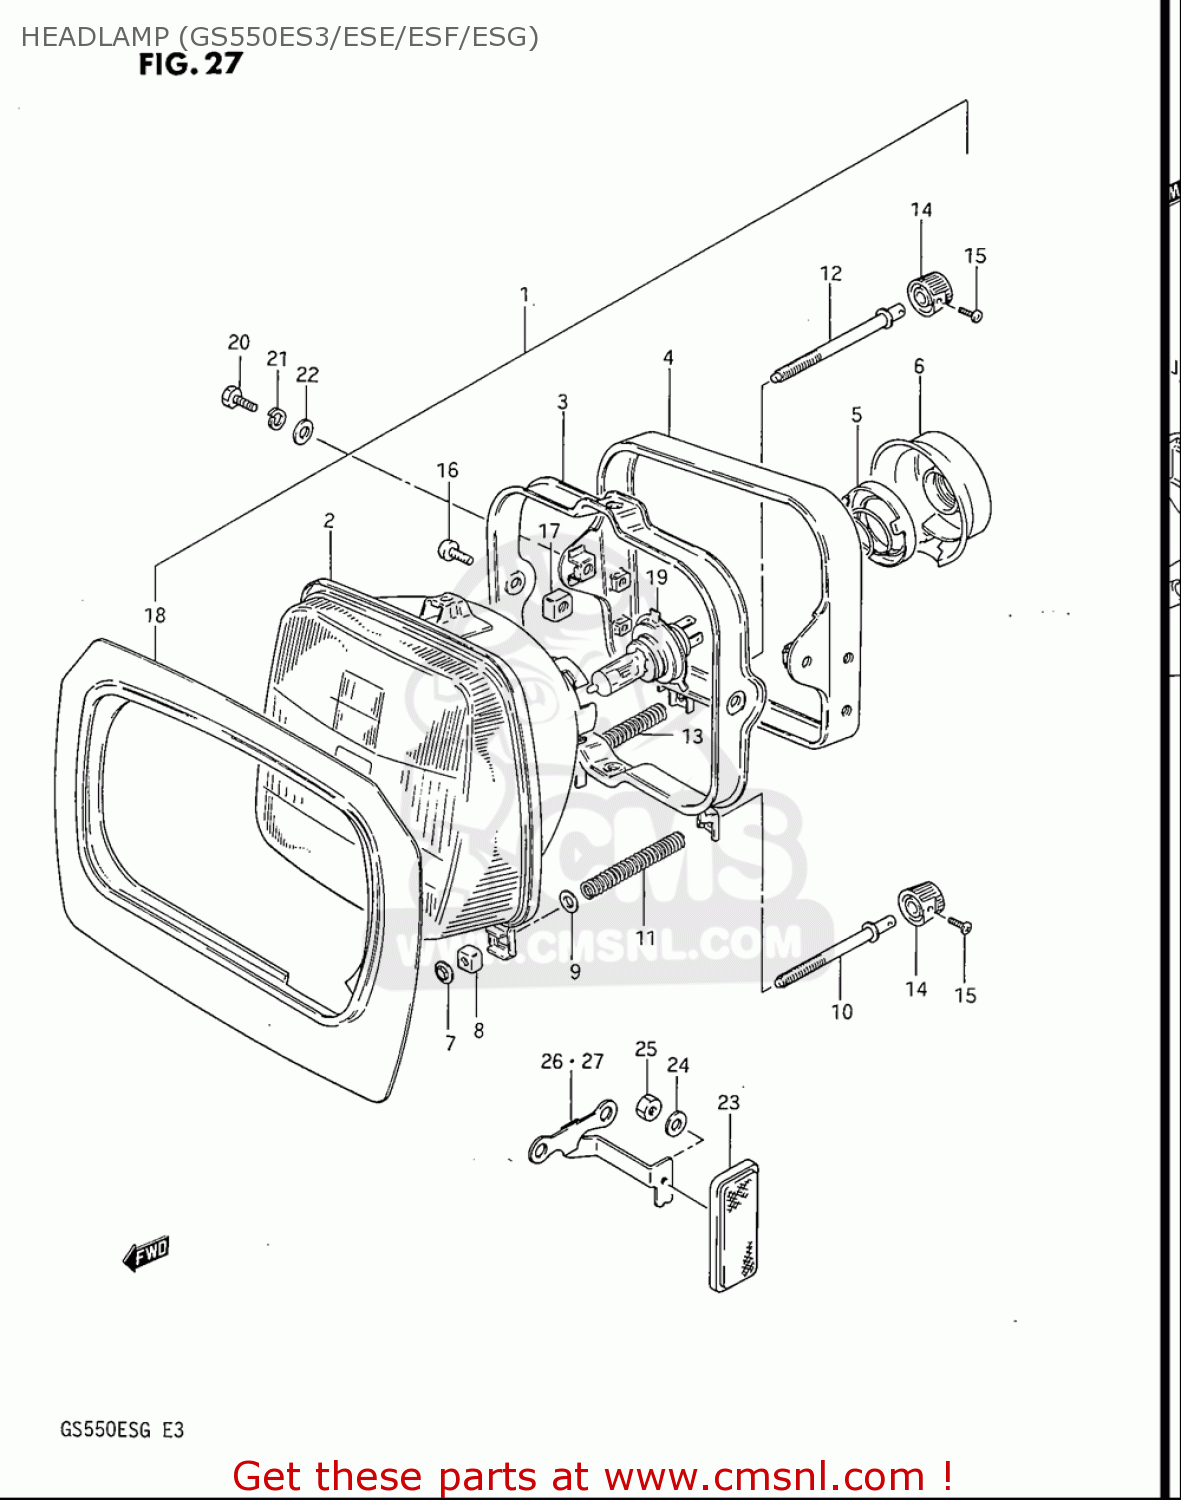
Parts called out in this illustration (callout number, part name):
3	RING,MOUNTING
5	HOLDER
6	COVER,SOCKET
7	NUT
9	WASHER(6.5X12X1.2)
10	SCREW,ADJUSTING
12	SCREW,ADJUSTING
14	SCREW
15	SCREW
16	SCREW
17	NUT
19	BULB(12V60/55W,H4)
20	BOLT
21	WASHER,LOCK
22	WASHER
23	REFLEX REFLECTOR,FR SIDE
24	WASHER
25	NUT
